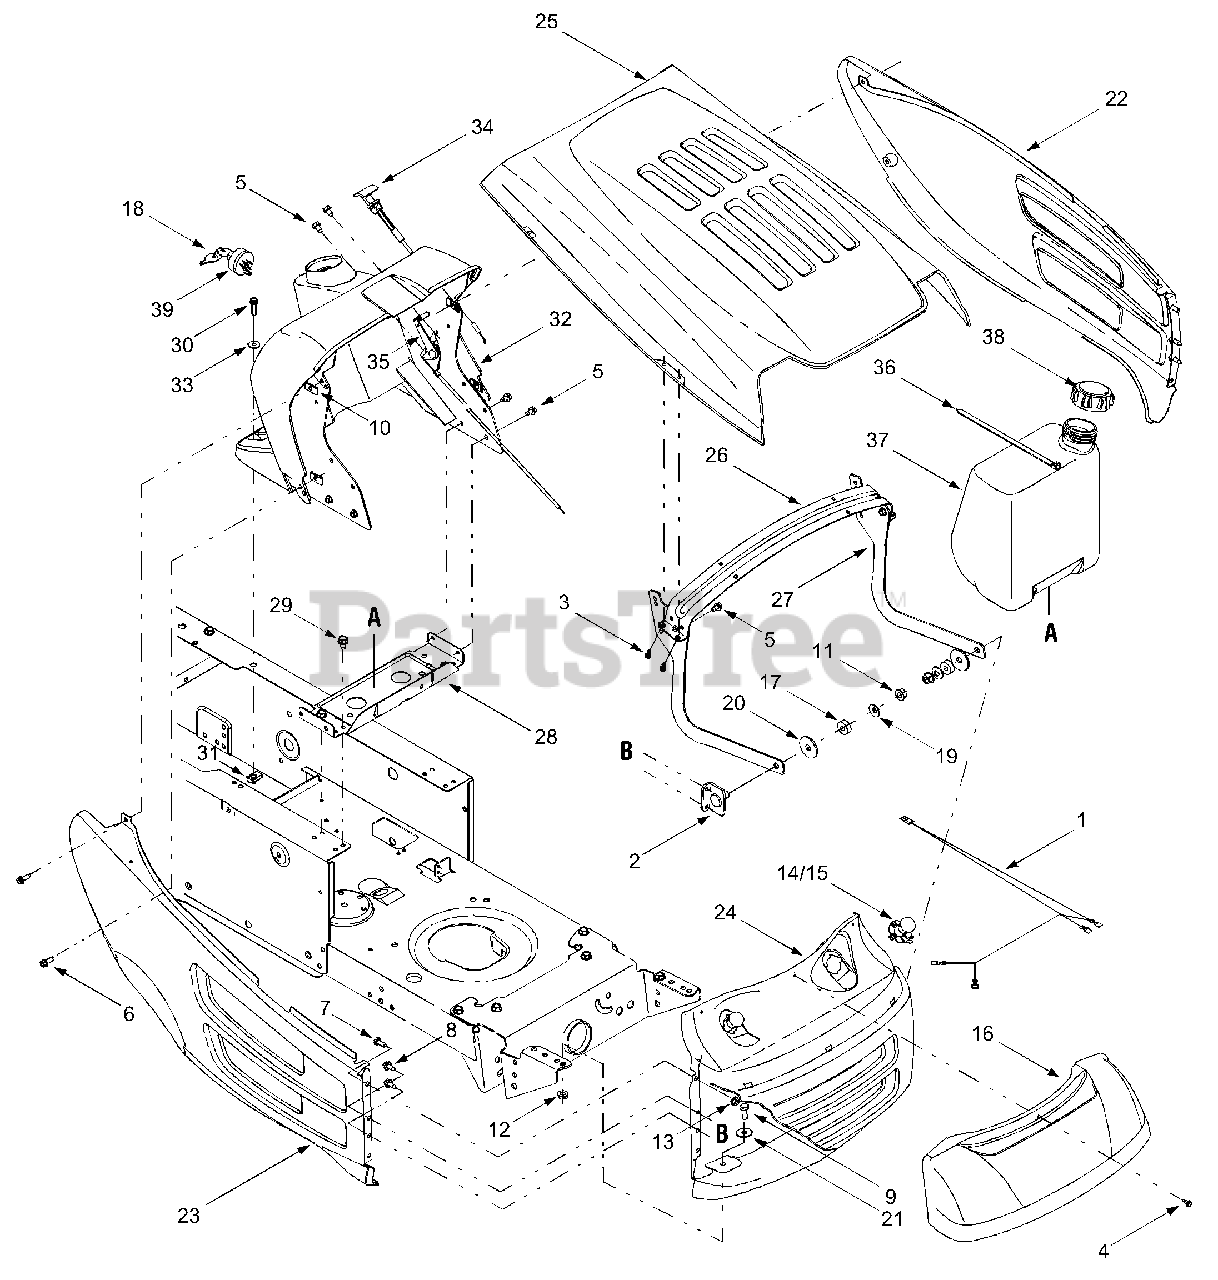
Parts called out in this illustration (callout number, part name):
1	Headlamp Harness Assembly
3	Screw, #10-16 x .50
4	Screw, #10-16 x .50
5	Self-tapping Screw, 1/4-20 x .5
6	Self-tapping Screw, 1/4-20 x .75
7	Hex Cap Screw:1/4-20 x .620
8	Hex Index Washer Screw, 1/4-14 x .0625
9	Hex Screw, 5/16-18 x .75
10	U-type Speed Nut, 1/4-20
11	Flange Lock Nut, 3/8-16
12	Lock Nut, 5/16-18
13	Flange Lock Nut, 1/4-20
14	Headlamp, 12V
15	Headlamp Socket
16	Headlight Lens (8-style)
17	Rubber Washer, .87 x .33
18	Keys (pair)
19	Flat Washer, .406 x .875 x .059
20	Flat Washer, .406 x 1.5 x 11 gauge
21	Flat Washer, .344 x 1.0 x .063
30	Self-tapping Screw, 1/4-20 x 1.0
31	U-type Speed Nut, 1/4-20
32	Dash Panel
33	Flat Washer, .260 x .720 x .060
34	Choke Control, 38"
35	Throttle / Choke Control, 18.5"
36	Cable Tie, 30.66
37	Fuel Tank, 1.5 gal.
38	Fuel Tank Cap
39	Ignition Switch, 6-pin
